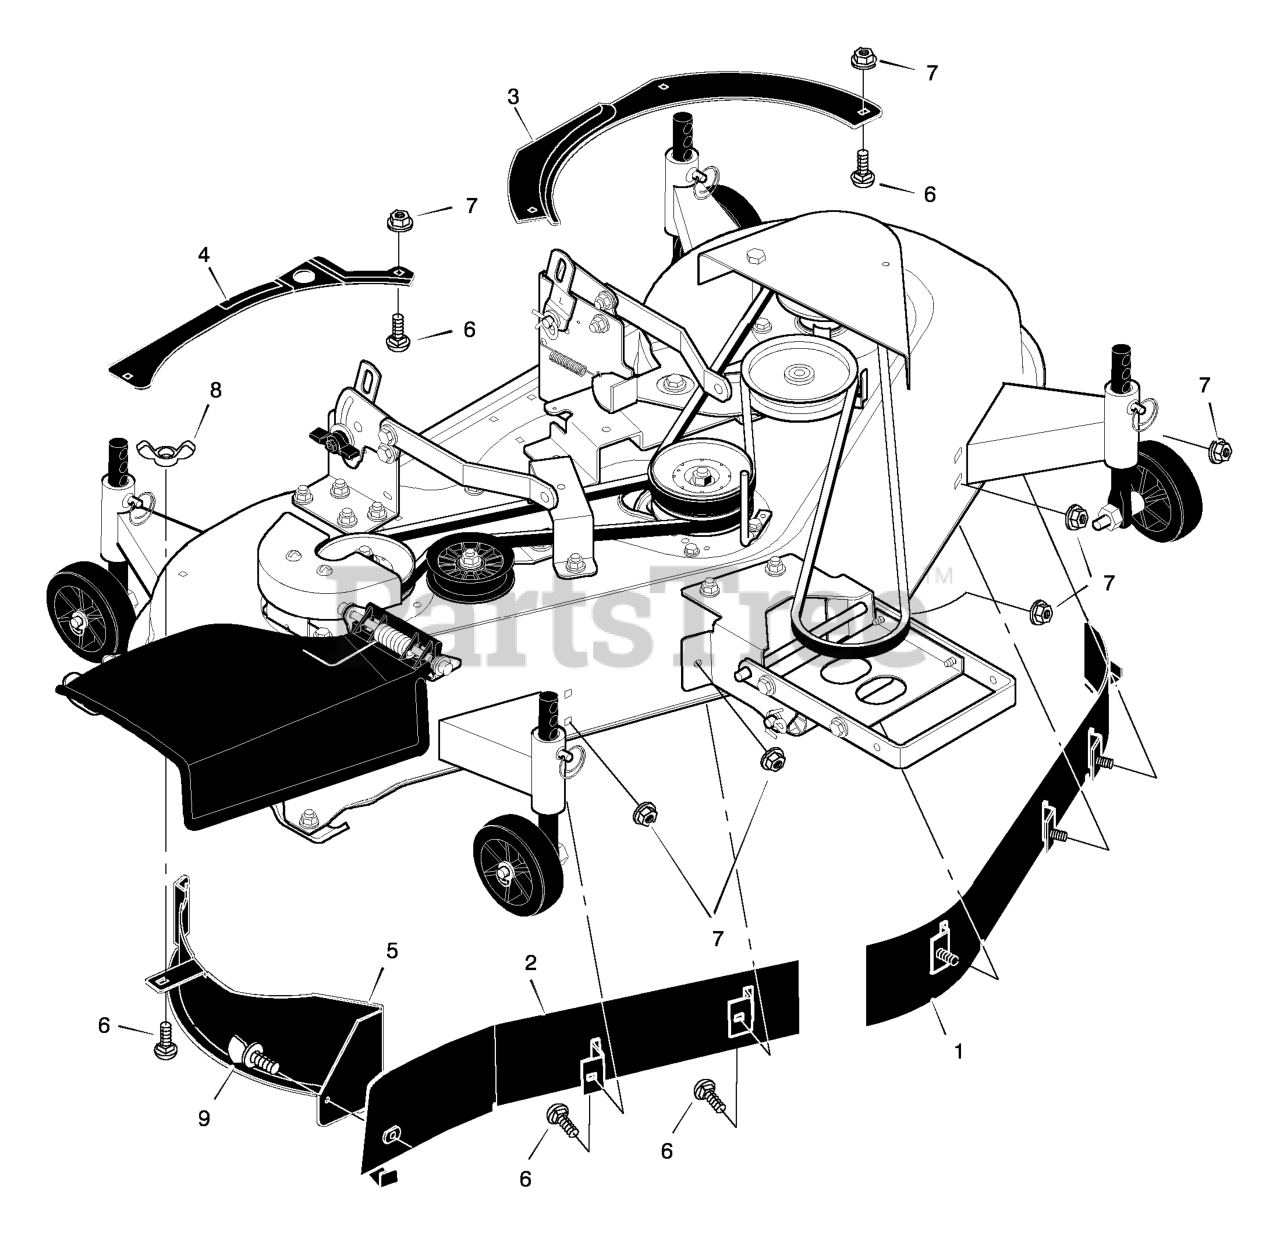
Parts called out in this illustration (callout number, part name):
1	Baffle, Left Front
2	Baffle, Right Front
3	Baffle, Left Rear
4	Baffle, Right Rear
5	Plate, Mulcher
6	Bolt, Carriage
7	Nut, Flange
8	Wingnut
9	Screw, Thumb
